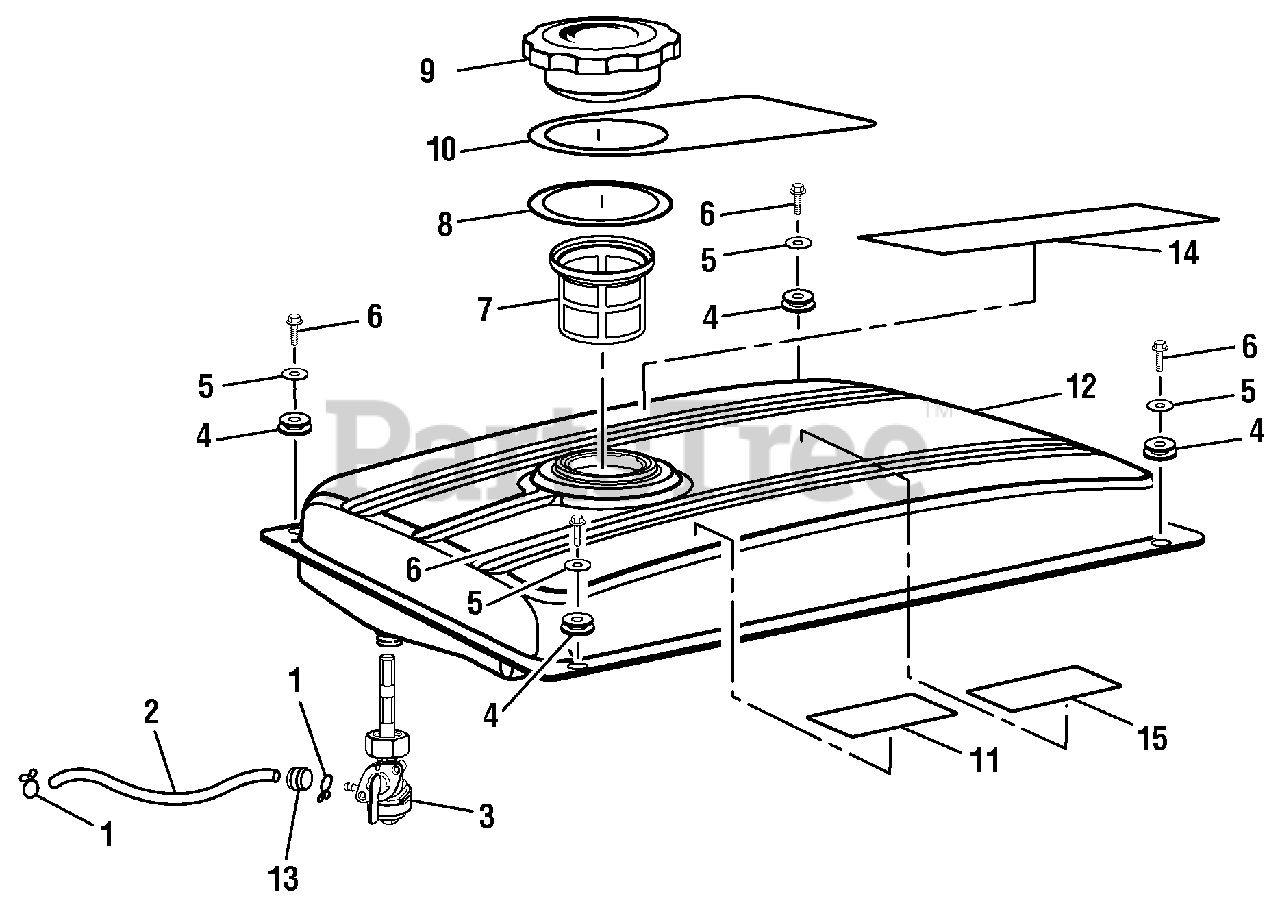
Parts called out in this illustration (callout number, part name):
1	Fuel Line Clamp
2	Fuel Line Hose
3	Fuel Valve Assembly
4	Bushing w/Insert
5	Washer (M6)
6	Bolt (M6 x 25 mm, Flange Hd.)
7	Fuel Tank Screen
8	Gasket (Fuel Cap)
9	Fuel Cap Assembly
10	Engine Warning Hang Tag
11	CPSC (English) Label
12	Fuel Tank
13	Grommet (Fuel Line)
14	Danger Label
15	E85 Label
